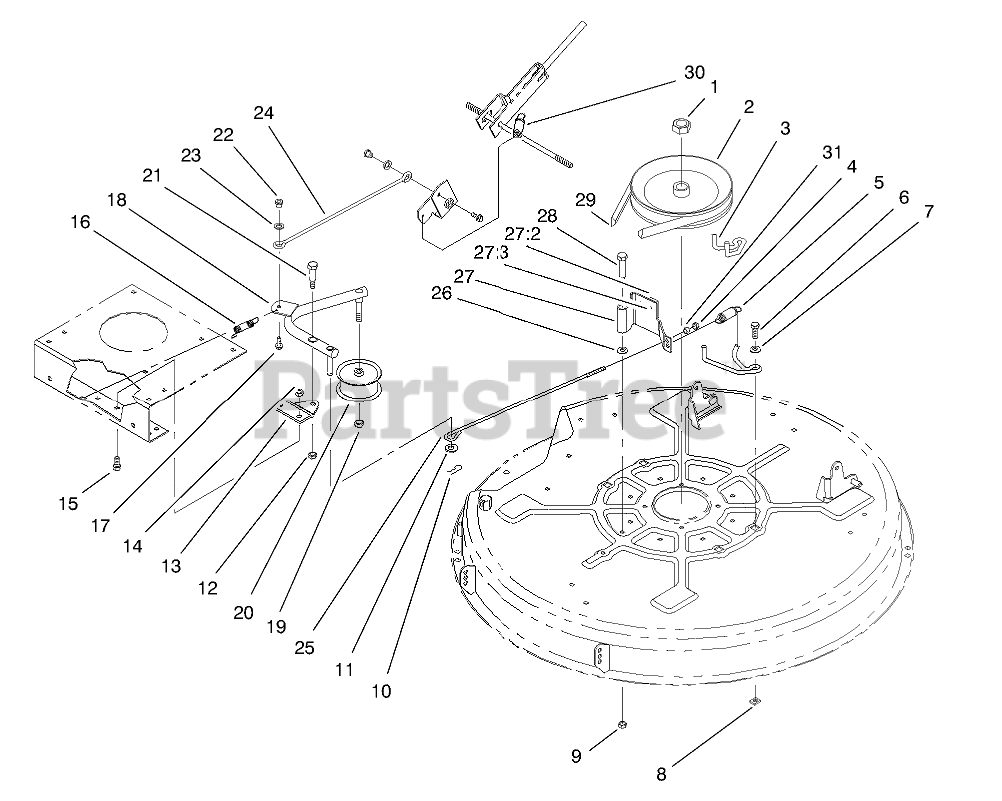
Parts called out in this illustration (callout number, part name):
1	NUT-HEX
2	PULLEY-DECK
3	GUIDE-BELT, DECK
4	NUT-LOCK, NI
5	SPRING-EXTENSION
6	SCREW-HH
7	WASHER-PIVOT
8	NUT-RETAINER
9	NUT-LOCK, NI
10	PIN-COTTER
11	WASHER-FLAT
12	NUT-LOCK, NI
13	PLATE-MOUNTING, IDLER
14	NUT-LOCK, NI
15	SCREW-HH
16	SPRING-RETURN, BRAKE
17	SCREW-HHF
18	ARM-IDLER WA (BLACK)
19	NUT-LOCK, NI
20	PULLEY-IDLER
21	SCREW-SHOULDER, HH
22	POST-MOUNTING, LINKAGE
23	WASHER-FLAT
24	ROD-ENGAGE, DECK
25	ROD-BRAKE, DECK
26	WASHER-PLAIN
27	BRAKE ARM ASM
27:2	PAD-BRAKE
27:3	RIVET-BLIND
28	BOLT-SHOULDER
29	V-BELT
30	CABLE SPRING ASM
31	BALL-SWIVEL, STOP
